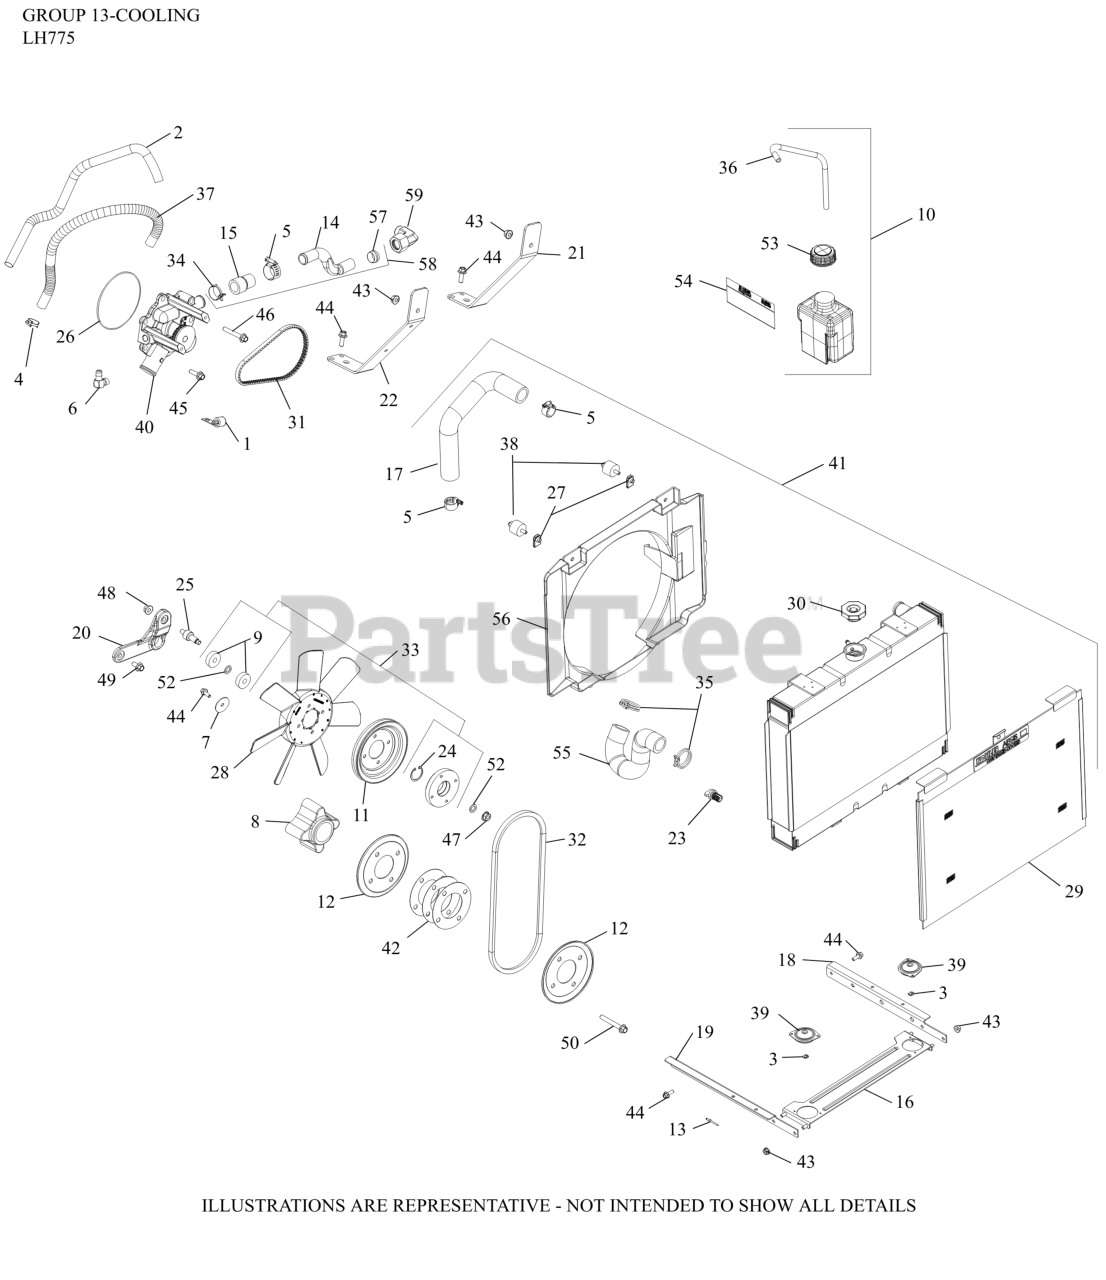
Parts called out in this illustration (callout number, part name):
2	SLEEVE, INSULATING 14"
5	CLAMP, HOSE
6	CONNECTOR
14	TUBE, CROSSOVER (METAL)
15	TUBE, CROSSOVER (RUBBER)
31	BELT, WATER PUMP
37	HOSE, BY-PASS (12.00")
40	KIT, WATER PUMP
45	SCREW, FLG M6x1.0x20
46	SCREW, FLG M6X1.0X40
